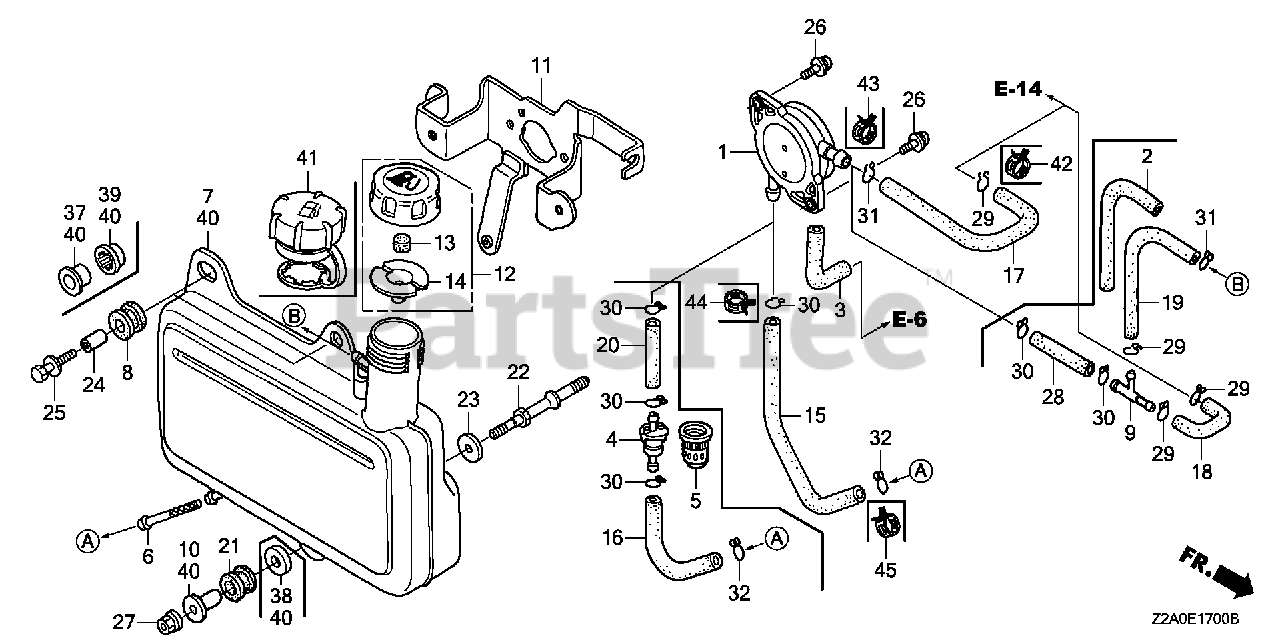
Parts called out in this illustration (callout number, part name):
1	PUMP ASSY., FUEL
3	TUBE, DIAPHRAGM
6	FILTER, FUEL
7	TANK, FUEL
10	COLLAR, FUEL TANK SETTING
11	STAY A, FUEL TANK
15	TUBE, FUEL TANK (FKM) (NA USE ALT:17701-ZL8-000)
17	TUBE, FUEL (FKM)
22	BOLT, FUEL TANK STUD (H=30MM)
23	WASHER (6MM)
25	BOLT-WASHER (6X25)
26	SCREW-WASHER (5X14)
27	NUT, FLANGE (6MM)
37	COLLAR, TANK SET
38	RUBBER A, TANK MOUNTING
39	RUBBER B, TANK MOUNTING
40	TANK KIT, FUEL
41	CAP ASSY., FUEL TANK
42	CLAMP, TUBE (D8)
43	CLAMP, TUBE (D8.5)
44	CLAMP, TUBE (D10)
45	CLAMP, TUBE (D12)
